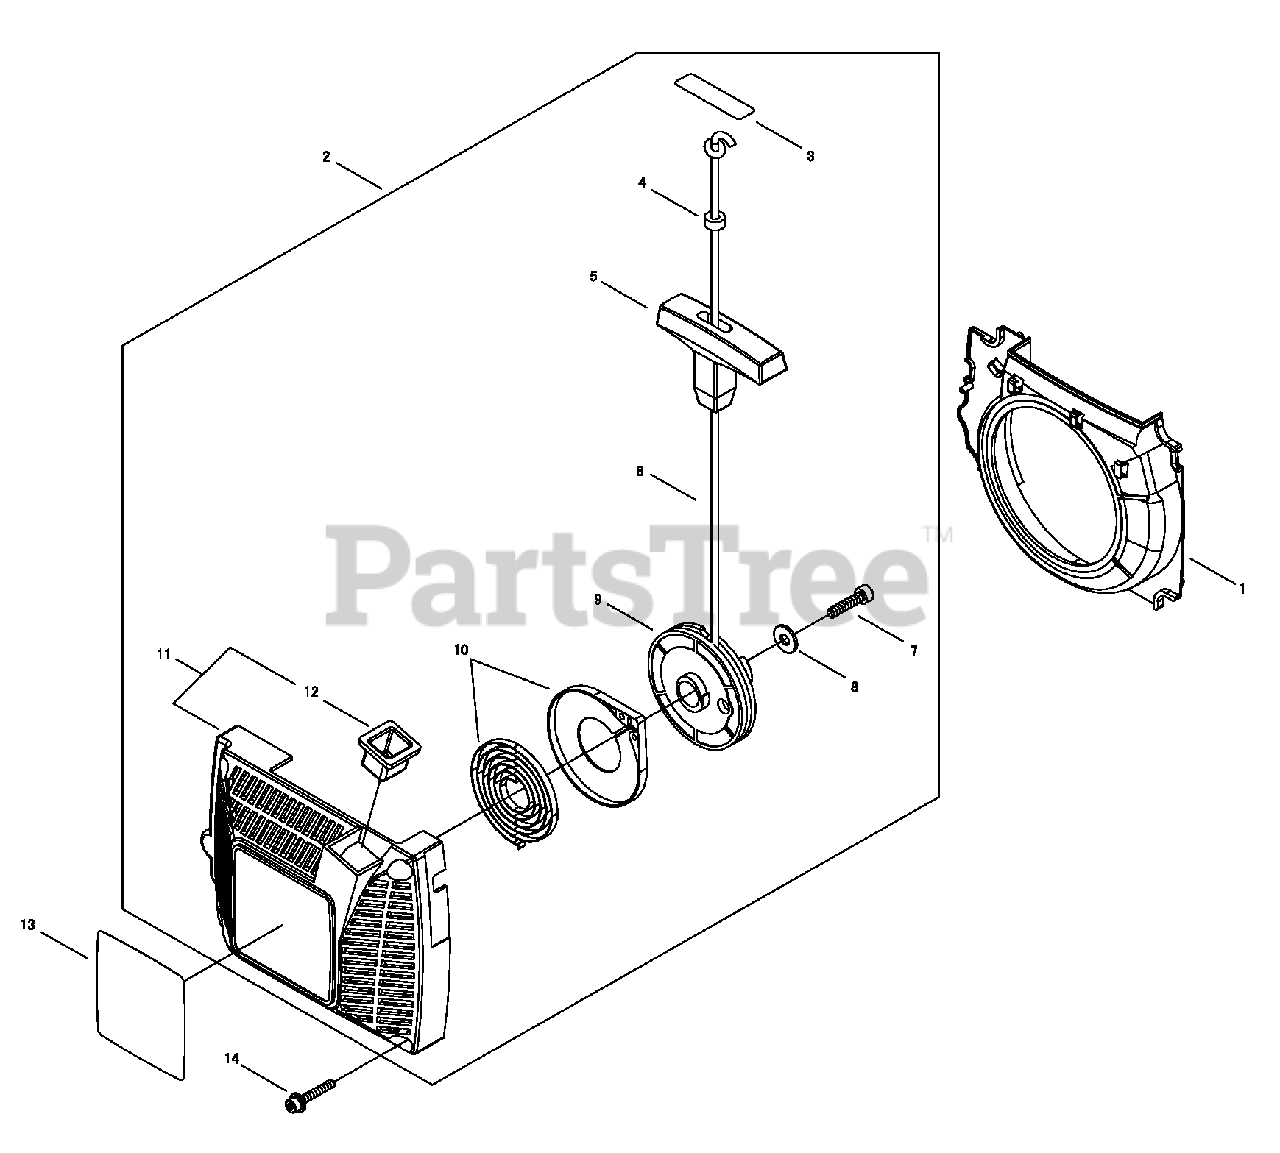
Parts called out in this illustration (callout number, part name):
1	PLATE, AIR
2	STARTER ASSY
3	TAPE
4	KNOB, STOPPER
5	RECOIL, KNOB
6	ROPE
7	BOLT 5×12
8	WASHER
9	REEL
10	SPRING, RECOIL
11	CASE, STARTER
12	GUIDE, ROPE
13	LABEL, TRADE
14	BOLT M4×16
